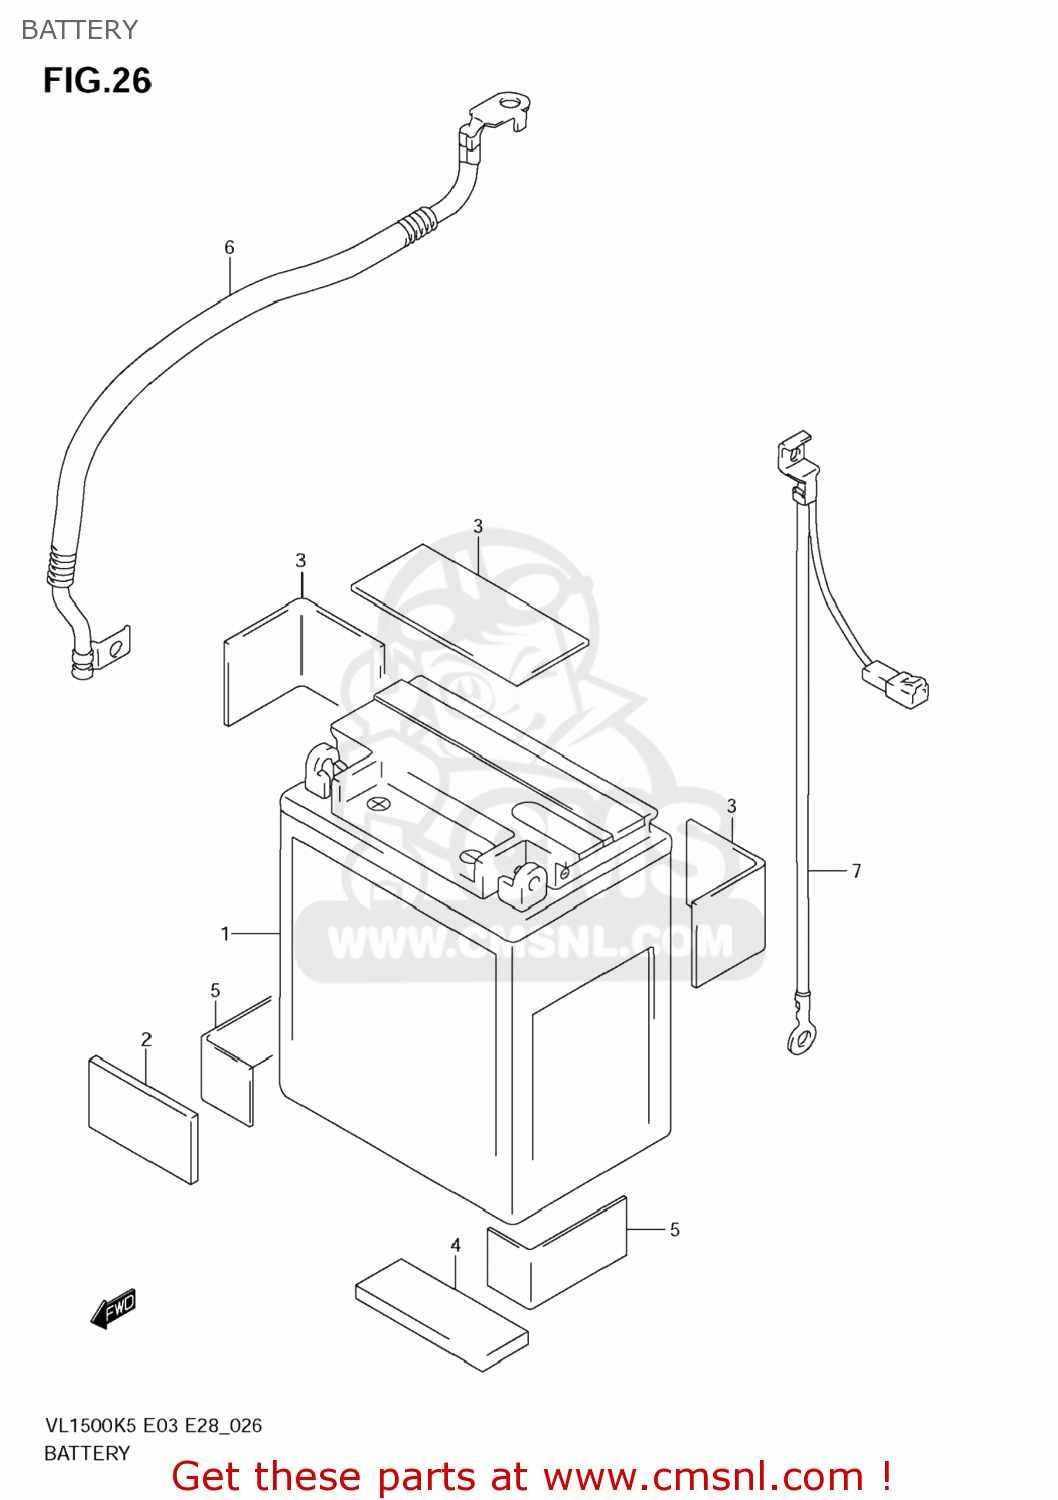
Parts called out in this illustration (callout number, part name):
1	BATTERY ASSY,F
2	PROTECTOR(40X70X5.0)
3	PROTECTOR(170X95X3.0)
4	PROTECTOR,BATTERY(50X90X4)
5	PROTECTOR(20X90)X4
6	WIRE,BATTERY PLUS LEAD
7	WIRE,BATTERY MINUS LEAD
